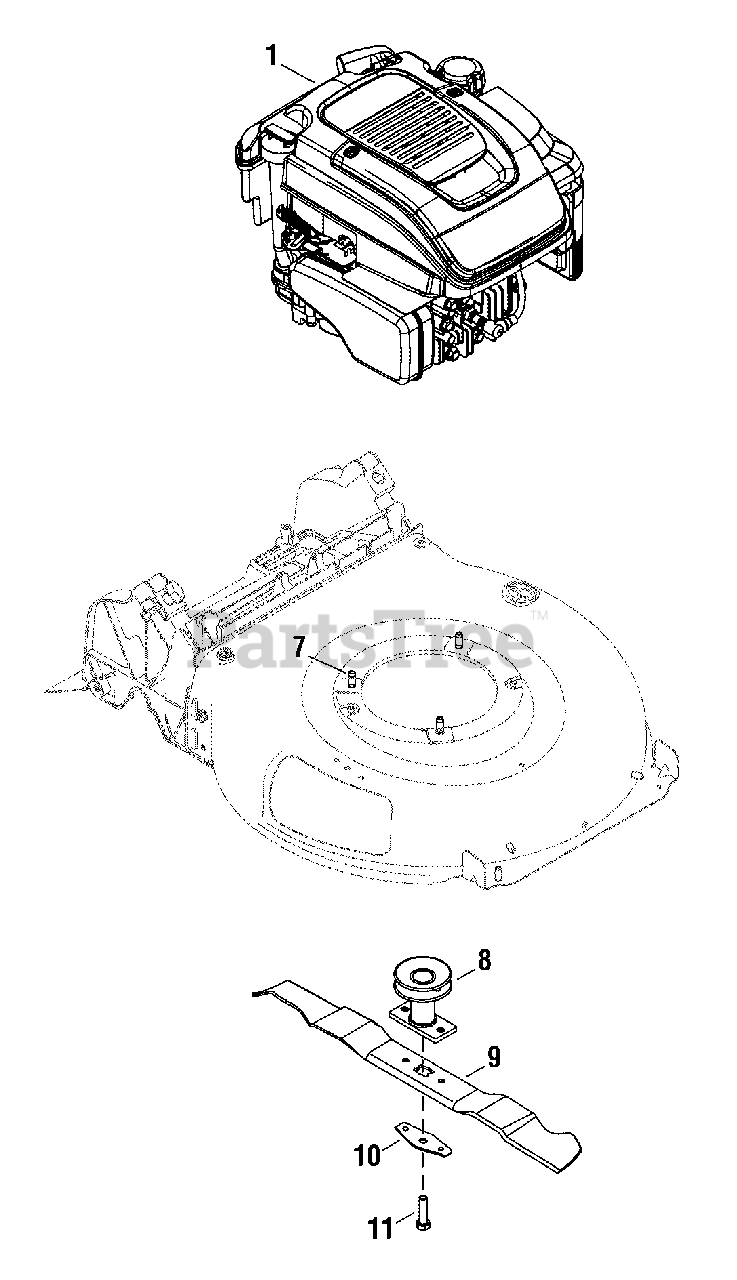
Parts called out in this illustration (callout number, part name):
1	* ENGINE, Briggs & Stratton, Mod. 111P02-0014 -F1
1	* ENGINE, Briggs & Stratton, Mod. 111P02-0983 -F1
7	SCREW, Engine Mounting, 3/8-16 x 1
8	ASSEMBLY, Blade Adapter
9	BLADE, Mulching
10	SUPPORT, Blade Bell
11	SCREW Hex, 3/8-24 x 1-1/2
